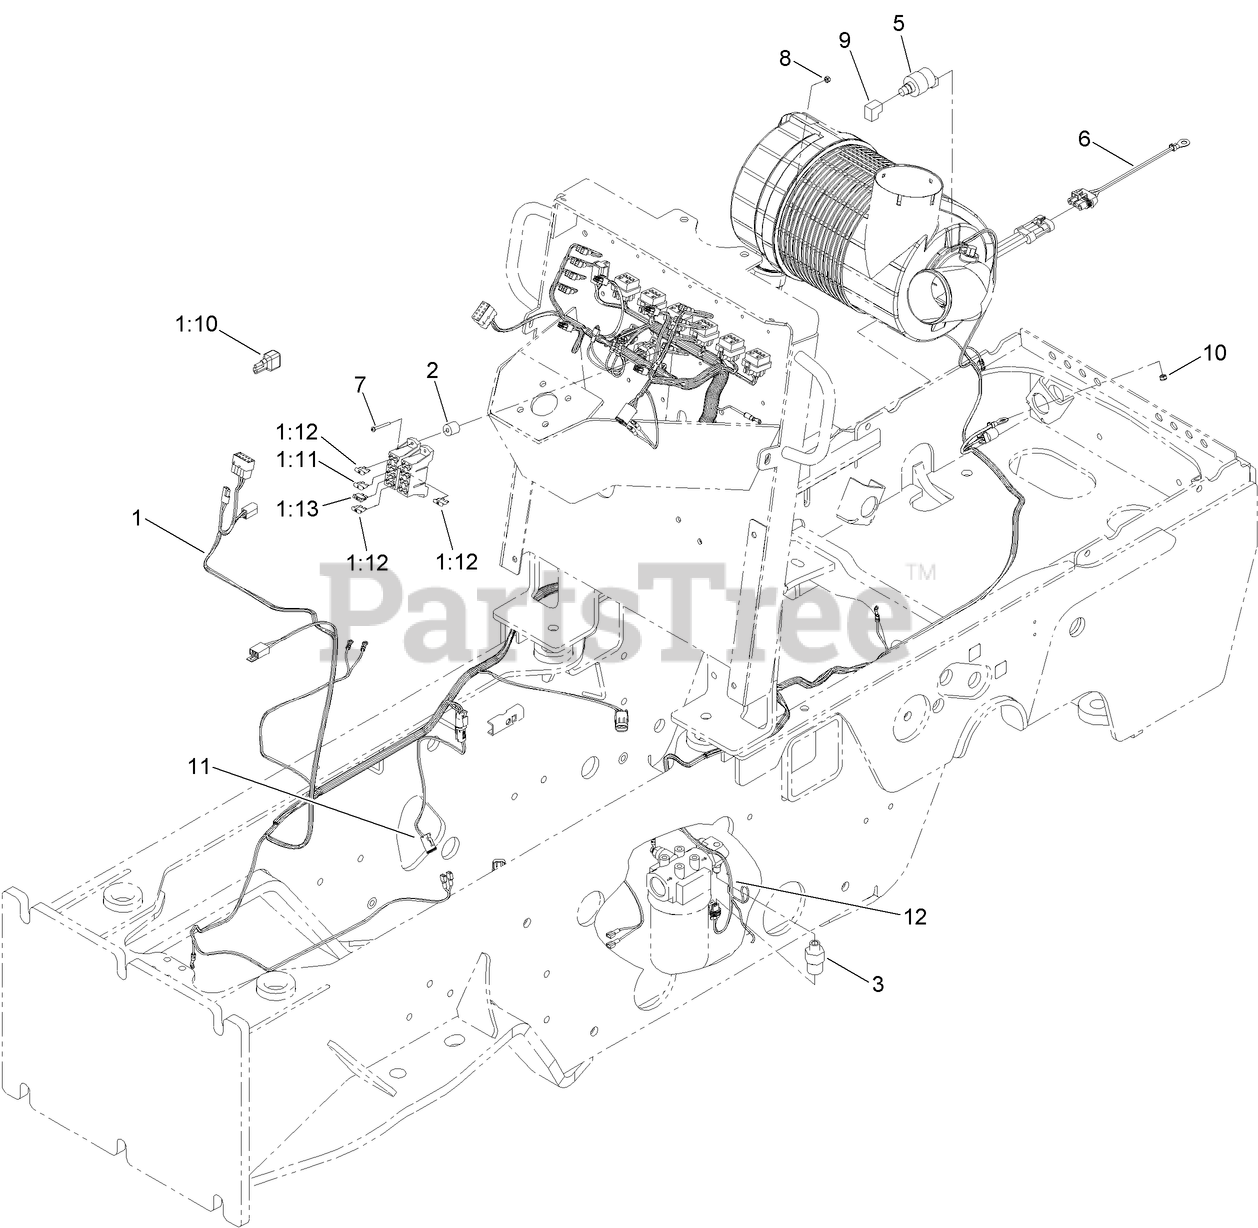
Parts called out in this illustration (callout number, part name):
1	WIRE HARNESS ASM
1:11	FUSE-2 AMP
1:12	FUSE-BLADE, 10 AMP
1:13	FUSE-BLADE, 15 AMP
2	SPACER
3	SWITCH-PRESSURE
5	SWITCH ASM
6	HARNESS-WIRE, FUSIBLE LINK
7	SCREW-PPH
8	NUT-LOCK
9	FITTING-ELBOW, 90
10	NUT-HEX
11	HARNESS-WIRE (HYD DRIVE EXTENSION)
12	HARNESS-WIRE (HYD TEMP EXTENSION)
